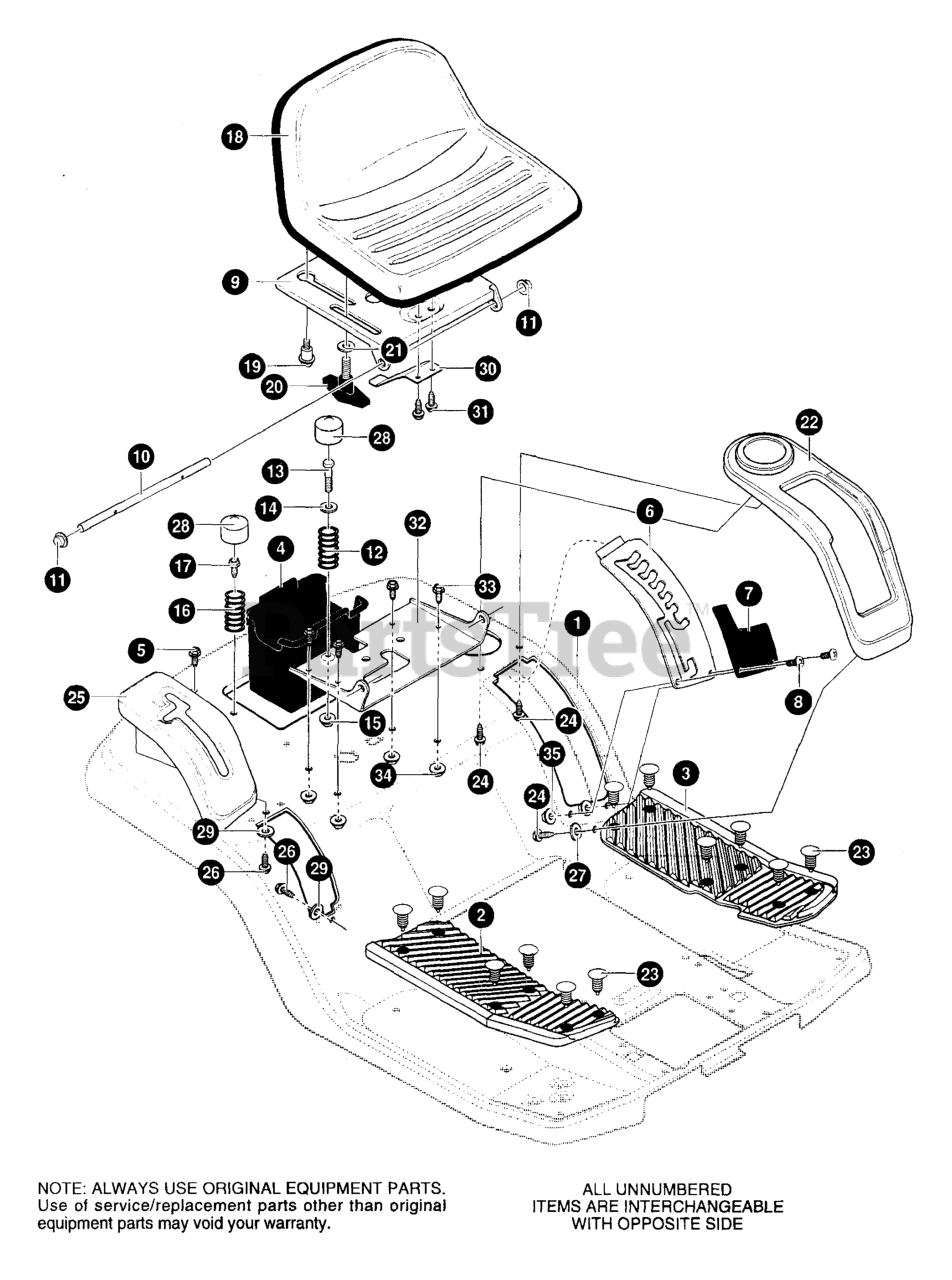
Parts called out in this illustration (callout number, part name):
1	SEAT DECK
2	FOOTREST PAD RH
3	FOOTREST PAD LH
4	CONTAINER, BATTERY
5	SCREW 1/4-20X.63 HHWATAPSER
6	PLATE, LIFT DETENT LG.
7	COVER, LIFT DETENT
8	SCREW, .230X.135 PPANTAP10-32B
9	SUPPORT, SEAT
10	ZINC HINGE SEAT PIVOT
11	NUT, PUSH CAP.375 (28X23)
12	SPRING, COMPRESS 4.57LGX1.17
13	BOLT, SHOULDER 1/4-20 NC-2A (9X55)
14	WASHER CUP ZINC
15	NUT, 1/4-20 WDFLLK 15X89
16	SPRING, COMPRESS 1.43LG 164X30
17	SCREW 5/16-18X.75 HHWATAPSGIB
18	SEAT, MV1500
19	BOLT, SHOULDER 5/16-18
20	BOLT, WING 5/16-18X.50 LG THRD
21	WASHER, FLAT .344 x .62 x .06
22	COVER, DETENT PLATE
23	FASTENER, RATCHET
24	SCREW, 1/4-15X.44/.53 HILOHHWA
25	COVER, HAND/FOOT HYDRO
26	SCREW, 1/4-15X.44/.53 HILOHHWA
27	FLATWASHER.286X.63X.065
28	CAP, HUB/SEAT SPRING
29	WASHER, FLAT.286X.63X.065
30	SPRING, LEAF
31	SCREW, 1/4-20X.50 WAHHTAP
32	BRACKET, PIVOT SEAT
33	SCREW 5/16-18X.75 HHWATAP
34	NUT 5/16-18 WDFLLK
35	NUT #10-32 CTRLK
